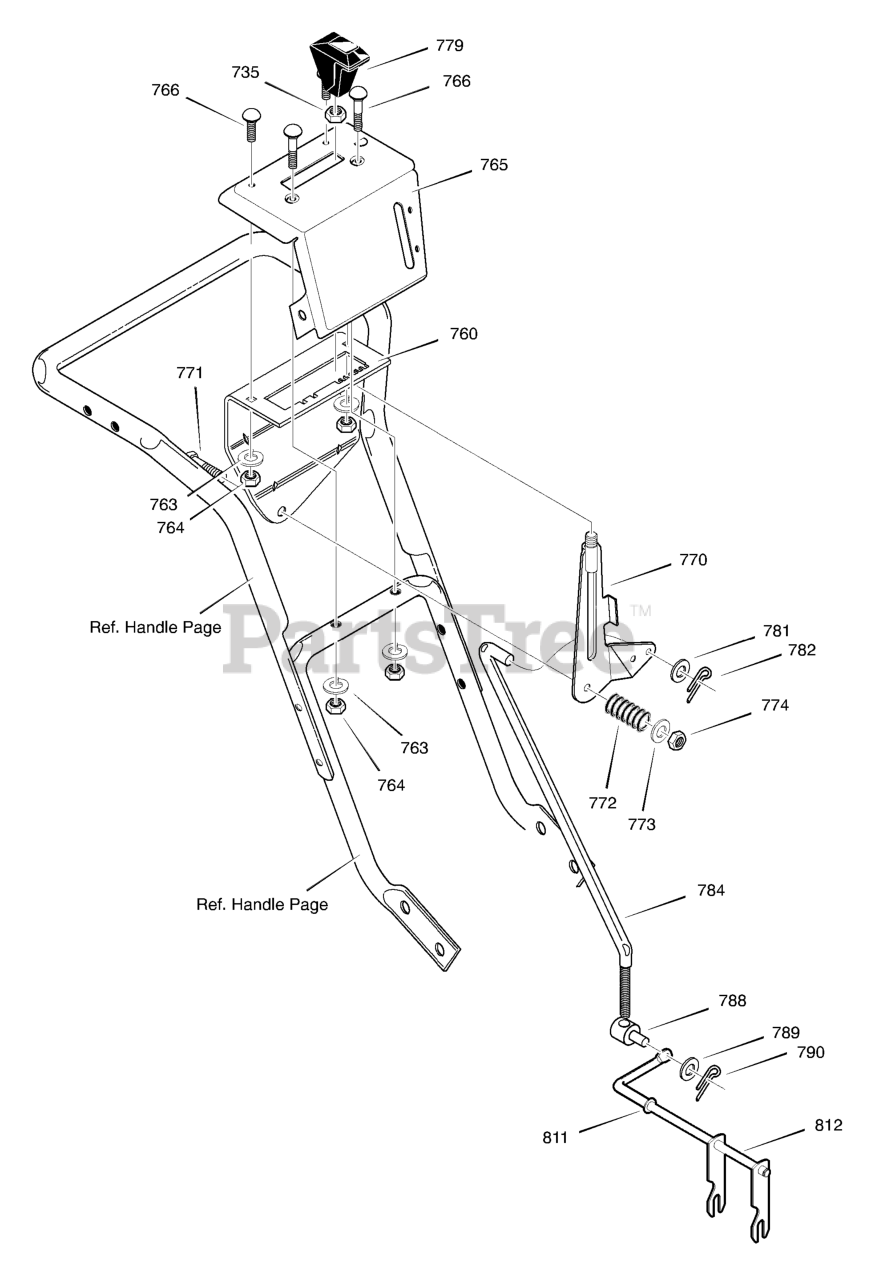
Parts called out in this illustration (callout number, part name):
735	NUT, 3/8-16 HEXJAM
760	BRACKET, SHIFT CONTROL
761	CARR. BOLT, 1/4-20 X 2
763	WASHER, HVSPTLK
764	NUT, 1/4-20 REGHEX
765	CONTROL PANEL
766	CARR. BOLT, 1/4-20 X 0.63
770	SHIFT LEVER ASSY
771	SCREW, 5/16-18 x 1.75
773	FLATWASHER
774	NUT, 5/16-18 HEXNYL
779	KNOB, SHIFT
781	WASHER, FLAT .349X.69X.066
782	PIN, COTTER
784	ROD, SPEED CONTROL
788	NUT, TRUNNION 5/16-24
789	WASHER, FLAT .349X.69X.066
790	PIN, COTTER
811	FLANGED BEARING
812	ROD ASSY, YOKE PANEL
813	RING, RETAINER
